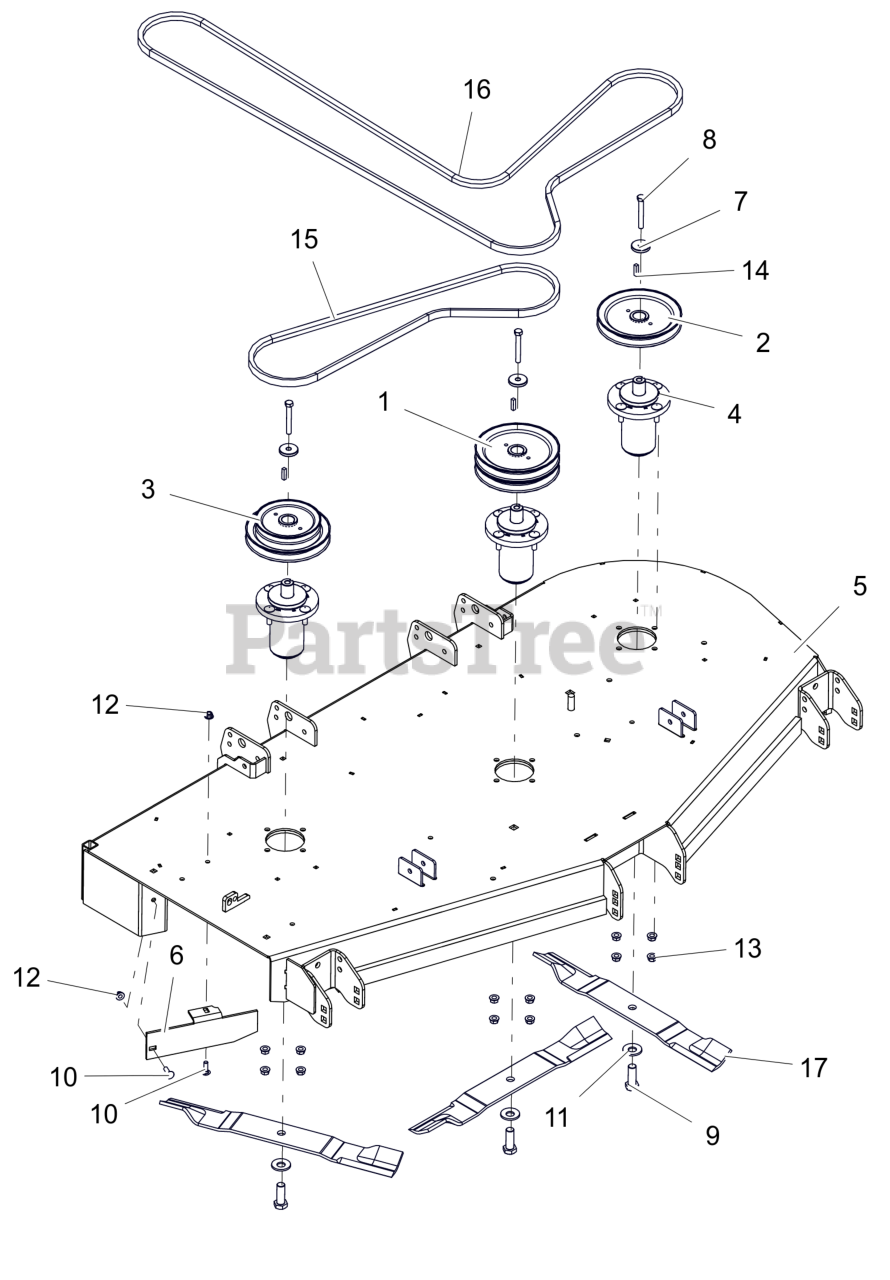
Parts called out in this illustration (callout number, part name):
1	PULLEY, DOUBLE 1.000 ID X 6.750 OD
2	PULLEY, V-1" ID X 6.75 OD
3	PULLEY, DBL-1"IDX6.75"&5.25"OD
4	ASM, MAINT FREE ALUM SPINDLE
5	WLDMT, PT160 SIDE DISCH DECK (RED)
6	60" DISCHARGE BAFFLE - RED
7	RETAINER, SHEAVE
8	BLT, HEX .38-16X2.75 G8 ZCC
9	BLT, HEX .62-18X1.75 G8 ZCC
10	BLT,RHSN .31-18X1.00 G5 ZCC
11	WSHR-BLVL .669X1.535X.138
12	NUT,NYL-FLG .31-18 GF ZCC
13	NUT-LK-CTR-FLG .375-16 GF ZCC
14	KEY, SQ .25X.25X1.00 RC 40-50
15	V-BELT, B-COGGED
16	BELT, B-SECTION EPDM RAW EDGE
17	BLADE, MOWER (20.50")
